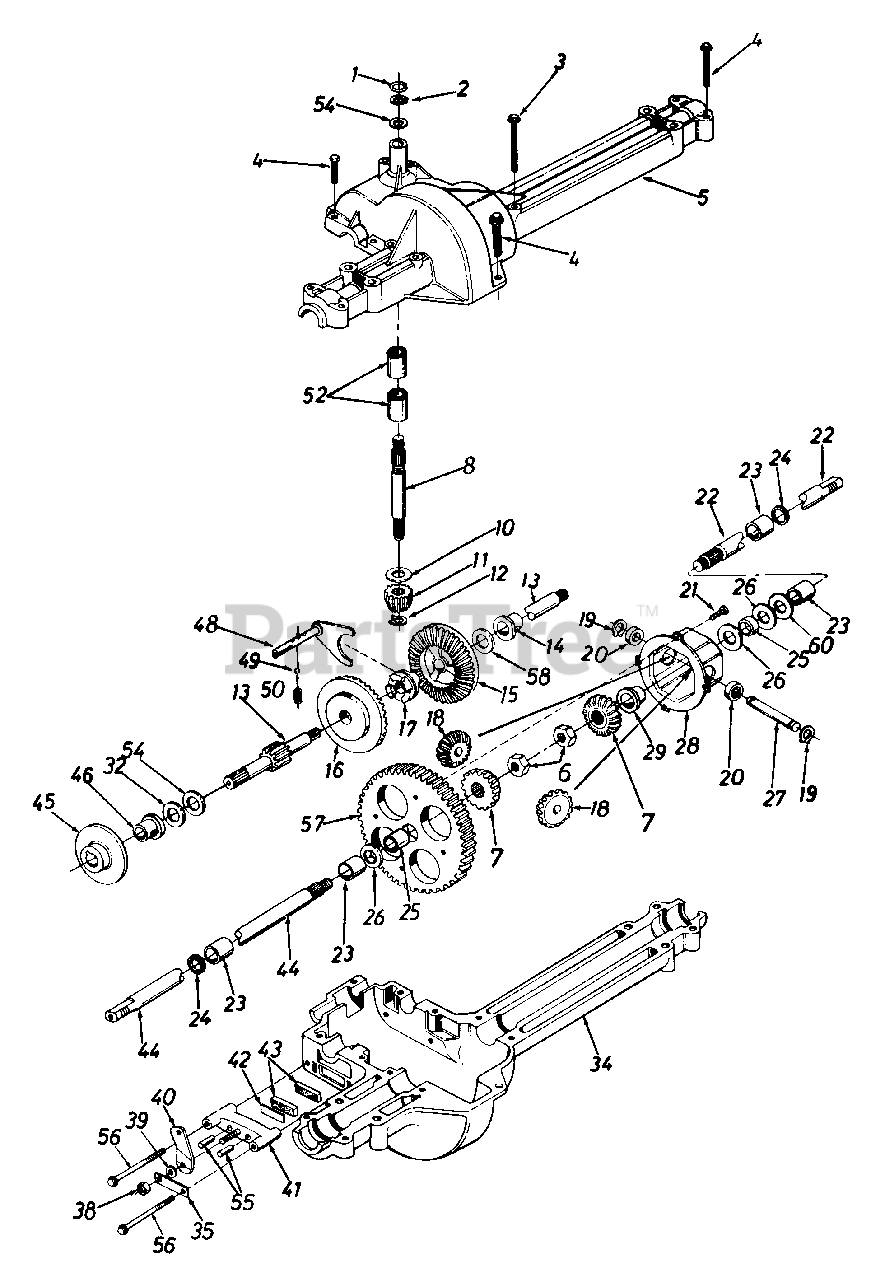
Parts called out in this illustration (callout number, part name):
1	Wire Ring
2	Retaining - Ring
3	Hex Bolt 1/4-20 x 1.75" Lg."
4	Hex Tap Scr. 1/4-20 x 1.25" Lg.
5	Upper Housing
8	Input Shaft
10	Thrust Washer 5/8" I.D. x 1.25" O.D.
11	Pinion Input 14T
12	Retaining Ring
13	Drive Shaft - L.H. Brake
14	Flange Brg. 5/8" I.D. x 3/4" Lg.
15	Bevel Gear 42T Small I.D.
16	Bevel Gear 42T Large I.D.
17	Clutch Collar
18	Miter Gear 15T (H.D.)
19	Retaining Ring
20	Thrust Bearing
21	Pan Head Scr. 1/4-20 x .50" Lg. w/Patch
22	Axle R.H. Ass'y.
23	Sleeve Bearing 3/4" I.D. x 1.0" Lg.
24	Oil Seal 3/4" I.D.
25	Axle Spacer
26	Fl - Wash. .760" I.D. x 1.5" O.D.
27	Cross Shaft
28	Differential Can Ass'y.
32	Thrust Wash. 5/8" I.D. x 1" O.D. x .025" Thk.Thk.
32	Fl - Wash. 5/8" I.D. x 1" O.D. x .030" Thk.
32	Thrust Wash. 5/8" I.D. x 1" O.D. x .035" Thk.
32	Fl - Wash. 5/8" I.D. x 1" O.D. x .040" Thk.
34	Lower Housing
35	Anti-Rotation Brkt.
38	Hex Nut 5/16-24 Thd.
39	Fl - Wash. .344" I.D. x .875" O.D.
40	Actuating Arm
41	Brake Yoke
42	Puck Plate
43	Brake Puck
44	Axle L.H. Ass'y.
45	Brake Disc
46	Flange Bearing 5/8" I.D. x 15/16" Lg.
48	Shift Fork Ass'y.
49	Ball Detent .250" Dia.
50	Spring Detent
52	Needle Brg. 5/8" I.D. x 1/2" Lg.
54	Fl - Wash. 5/8" I.D. x 1" O.D. x .020 Thk.
55	Actuating Pin 5/16" Dia.
56	Hex Wash Hd. Self-Tap Scr. 1/4-20 Thd.
57	Differential Gear 58T
58	Fl - Wash. 5/8" I.D. x 1" O.D. x .020 Thk.
58	Thrust Wash. 5/8" I.D. x 1" O.D. x .025" Thk.
60	Fl - Wash. .76" I.D. x 1.5" O.D. x .010" Thk.
60	Fl - Wash. .76" I.D. x 1.5" O.D. x .020" Thk.
60	Fl - Wash. .76" I.D. x 1.5" O.D. x .030" Thk.
60	Fl - Wash. .76" I.D. x 1.5" O.D. x .060" Thk.
60	Grease - Shell (15 oz.)
